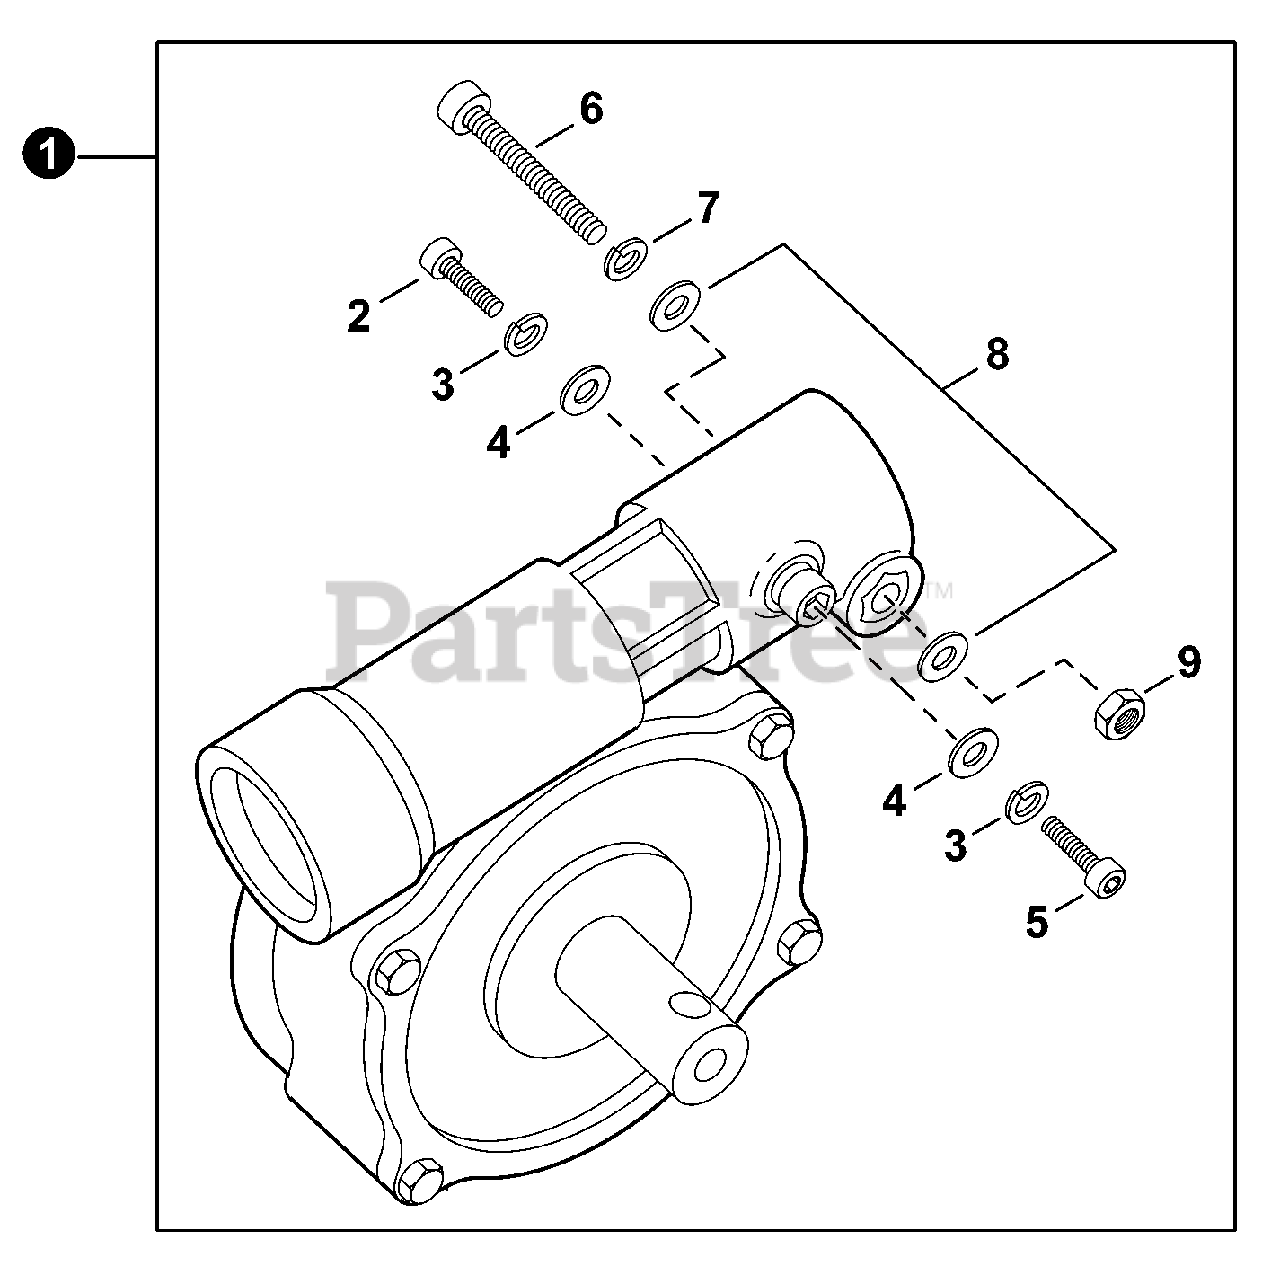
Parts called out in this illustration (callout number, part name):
1	GEAR CASE ASSY
2	BOLT 5×12
3	WASHER, SPRING 5
4	WASHER, FLAT 5.5×10×0.8
5	BOLT 5×8×0.80
6	SCREW, SOCKET HEAD 6×30
7	WASHER, LOCK M6
8	WASHER M6
9	NUT, HEX M6
